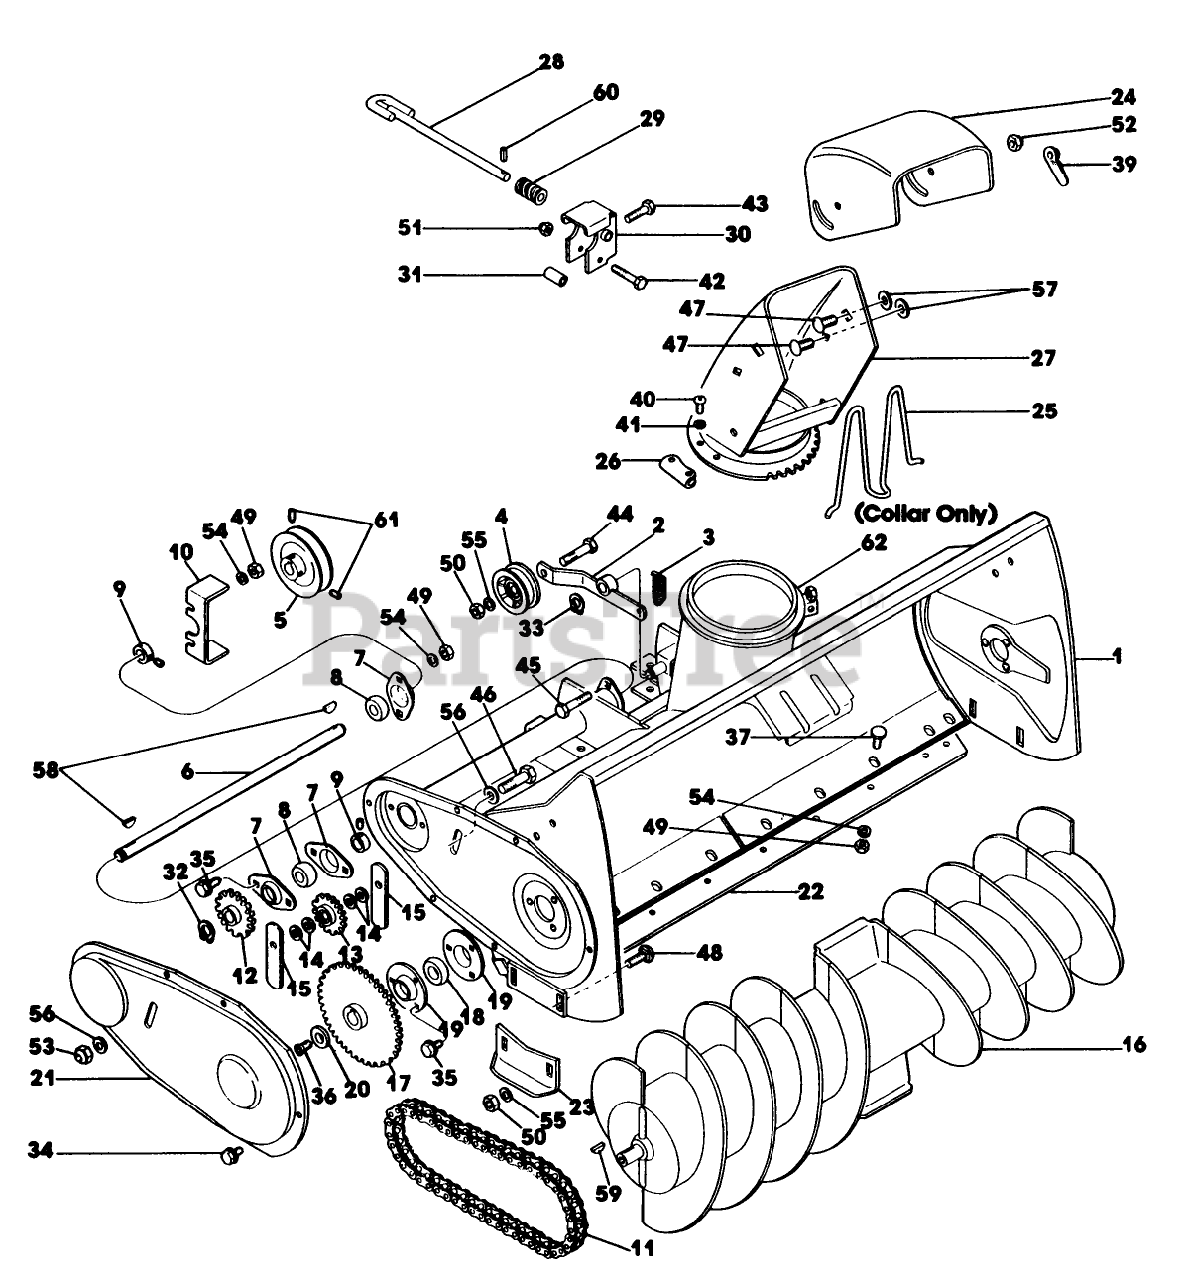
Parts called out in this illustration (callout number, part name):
23	Skid
30	Worm Support
54	Lock Washer 5/16 Plated
